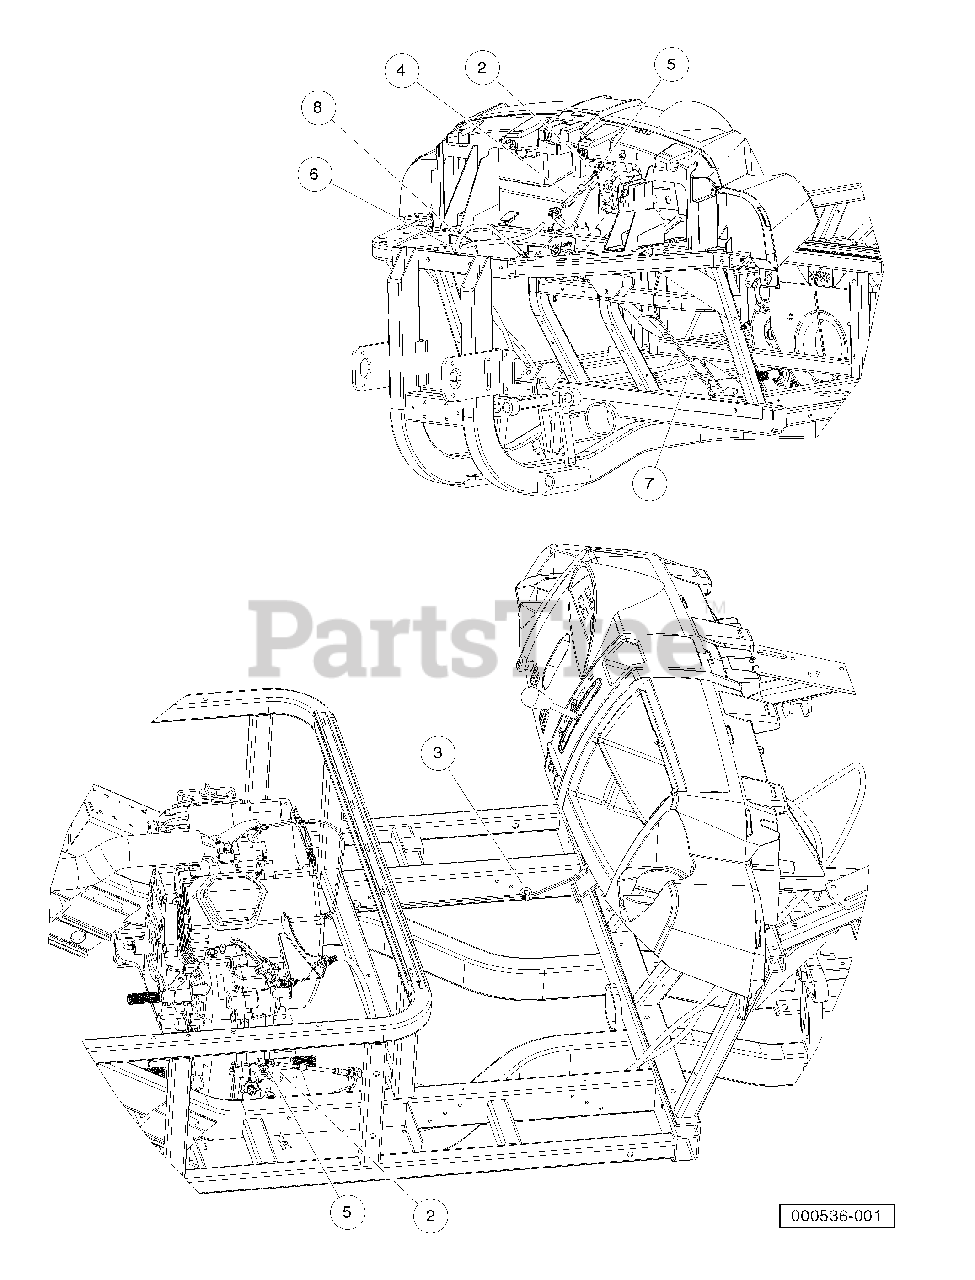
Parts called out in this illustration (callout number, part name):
1	Instl, Cables, Gas
2	Nut, 1/4-28 Hex Jam
3	Clip, Brake Line
4	Cable, Transmission Shift
5	Joint, Ball, .346 Dia
6	Cable, Accelerator, AWD, Gas
7	Cable, Choke, AWD
8	Tie Wrap, 8" Nylon
